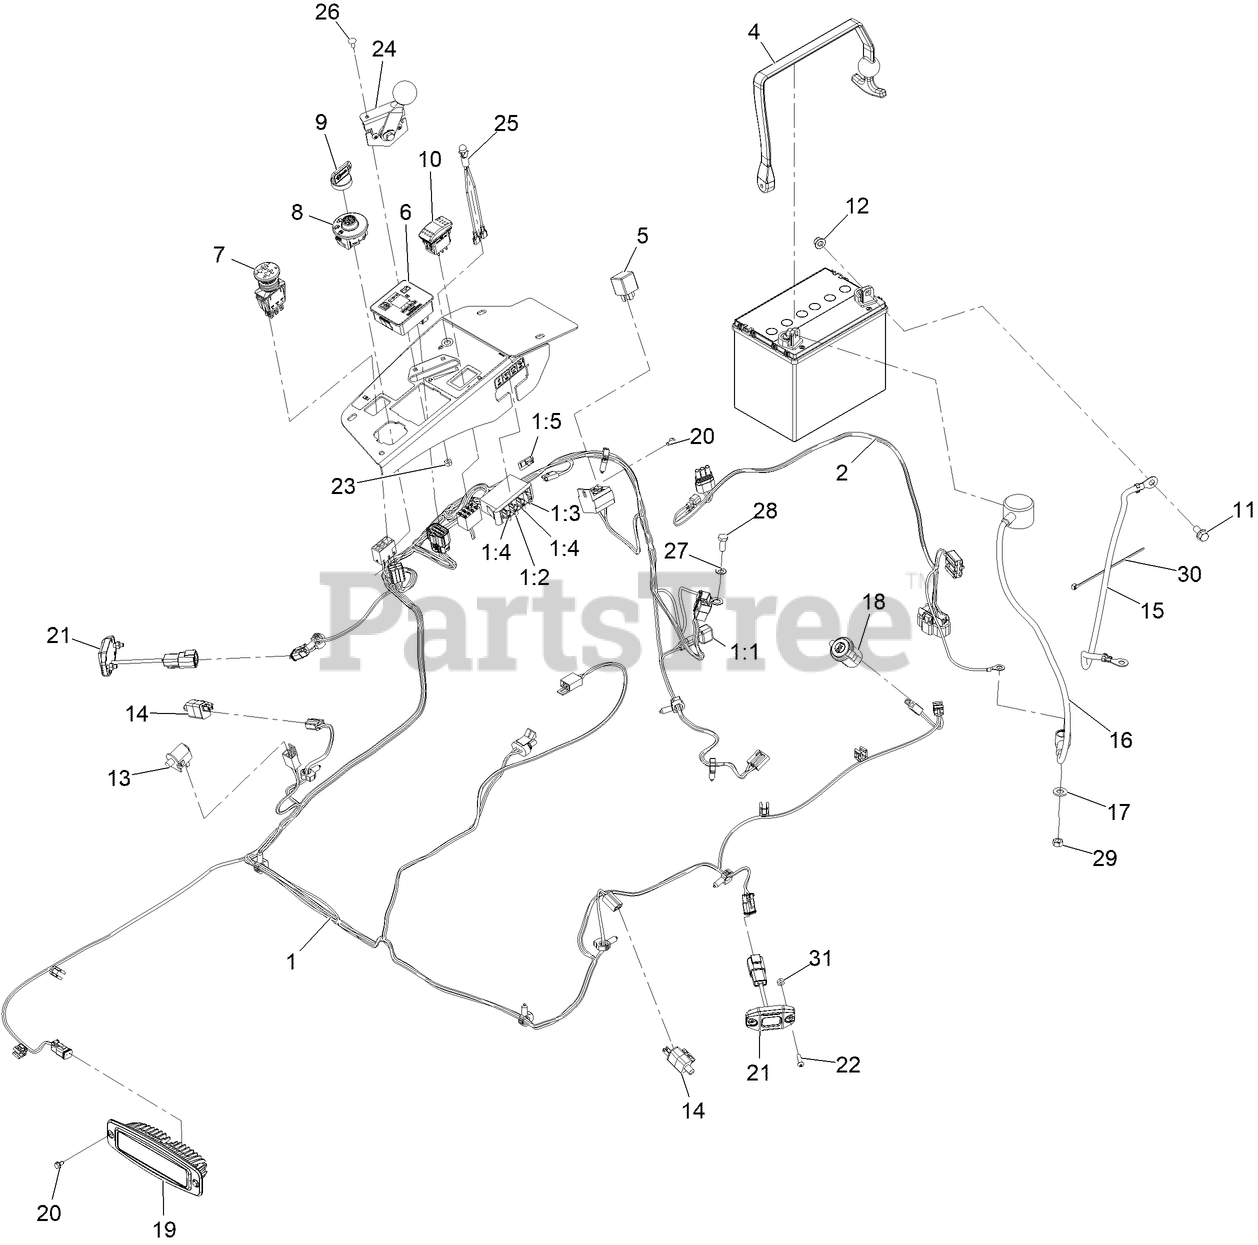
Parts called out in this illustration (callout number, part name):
1	HARNESS-MAIN LRX CARB
1:2	FUSE-BLADE, 10 AMP
1:3	FUSE-BLADE, 15 AMP
1:4	FUSE-BLADE, 25 AMP
1:5	CAP-PLUG
2	Harness-Adapter EFI, Etc
4	Strap-Bungee
6	FUEL/HOUR METER ASM
7	SWITCH, PTO 10A
8	SWITCH-IGNITION
9	KEY-IGNITION
11	SCREW-HHF
12	NUT-HF, NI
13	SWITCH-BAIL
15	CABLE-BATTERY, NEGATIVE
16	CABLE-BATTERY, POSITIVE
17	WASHER-FLAT
18	PORT-POWER, USB
19	MOUNT-FLUSH, LIGHT
20	SCREW-HWH
21	LIGHT-ROCK
22	Screw-HSBH
23	NUT-LOCK, NI
24	THROTTLE CONTROLLER-ETC
25	INDICATOR-LED, RED
26	BOLT-CARR
27	WASHER-LOCK
28	SCREW-HH
29	NUT-HEX
30	TIE-CABLE
31	Nut-Speed
